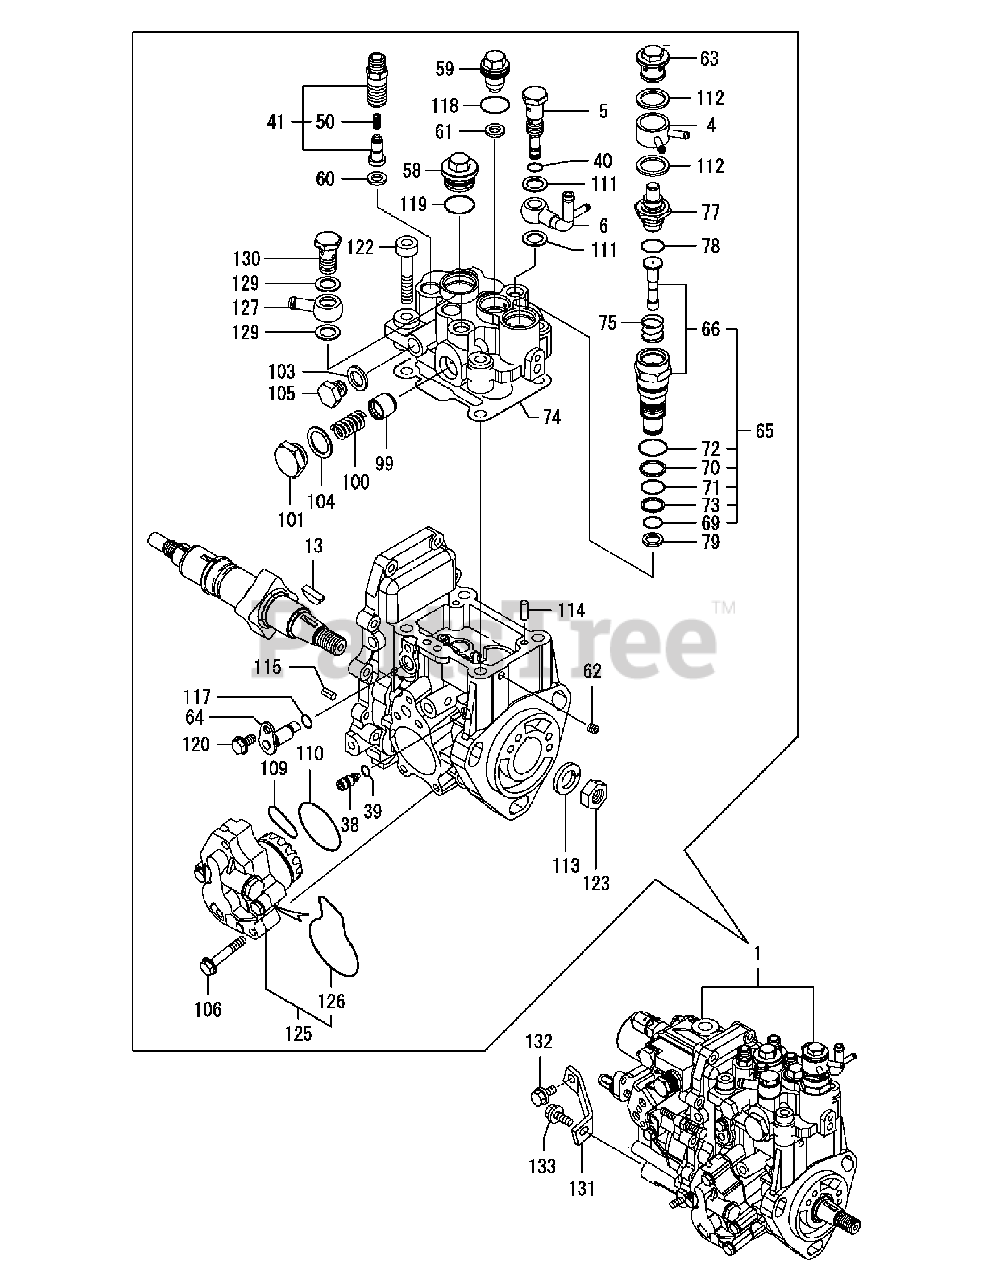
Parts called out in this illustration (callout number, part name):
1	INJECTION PUMP ASSY
4	JOINT, COOLING WATER
5	JOINT, OVER FLOW
6	JOINT, OVER FLOW
13	KEY, WOODRUFF 4X16
38	STOPPER, TAPPET
41	SETTING, DELIVERY
50	SPRING, DELIVERY
60	PK(BARREL PLUG
61	PK(BARREL PLUG
63	PLUG, WATER PUMP
66	TIMER CMP
73	RING, BACKUP T2 P 15
77	ELEMENT, THERMO
100	SPRING, ACTUATOR
103	SEAL WASHER 12
111	SEAL WASHER 12
113	SPRING WASHER 14
114	PARALLEL PIN 5X14
115	SPRING PIN 5X10
117	O-RING 1A P-7.0
120	BOLT 6X 10 PLATED
123	LOCK NUT M14 PLATED
125	PUMP ASSY, FUEL FEED
127	JOINT, PIPE 12
129	SEAL WASHER 12
130	JOINT BOLT 6,PIPE
131	RETAINER, PUMP
132	BOLT M 8X 16 PLATED
133	BOLT M 8X 20 PLATED
